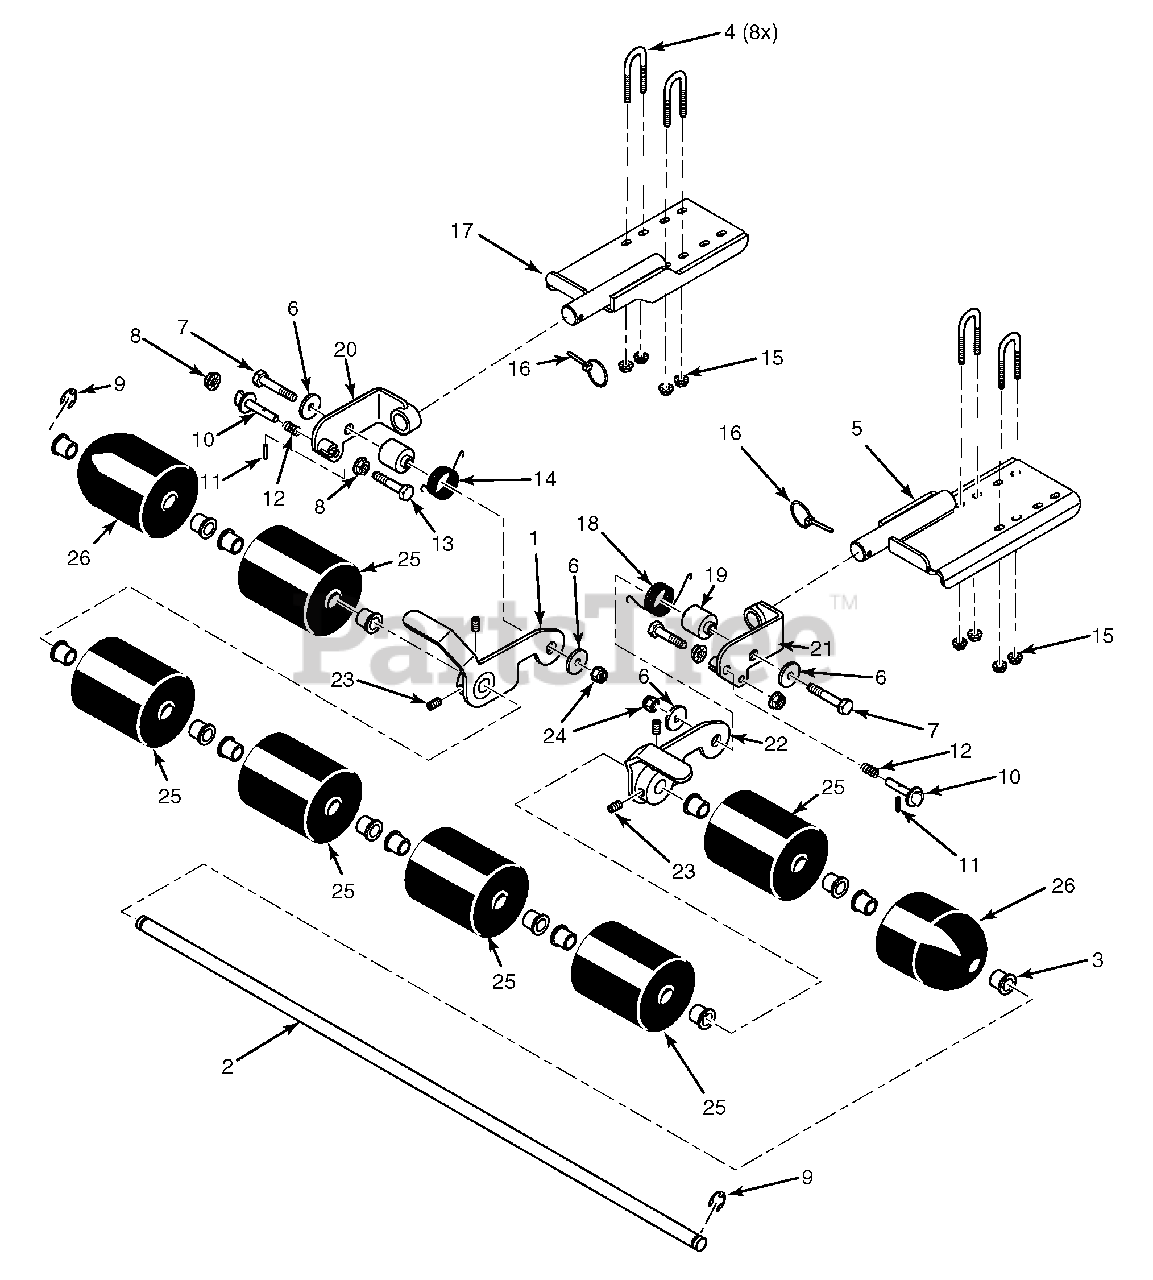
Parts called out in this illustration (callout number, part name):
1	Hinge Weldment, L.H.
2	Roller Shaft
3	Bushing, .752 Oilite
4	U-Bolt, 1/4-20 x 3/4"
5	Mounting Bracket Weldment, SCZ LH.
6	Flatwasher, 3/8-.406 x 1-1/2" 7 Gauge
7	Bolt, Hex Head 3/8-16 x 2-3/4"
8	Nut, Serrated Flange 3/8-16
9	Retaining Ring, .750 External "E"
10	Pin, Lift Latch
11	Pin, Slotted Spring .156 x 3/4"
12	Spring, Lock Pin
13	Bolt, Hex Head 3/8-16 x 2-1/2"
14	Spring, Torsion L.H.
15	Nut, Serrated Flange 1/4-20
16	Quick Pin, .188 Dia.
17	Mounting Bracket Weldment, SCZ R.H.
18	Spring, Torsion R.H.
19	Hub, Striper
20	Pivot Weldment, L.H.
21	Pivot Weldment, R.H.
22	Hinge Weldment, R.H.
23	Set Screw, 3/8-16 x 1/2"
24	Nut, Elastic Stop 3/8-16
25	Roller Assembly
26	Roller Assembly, Striper End
27	Hinge Weldment, L.H.
